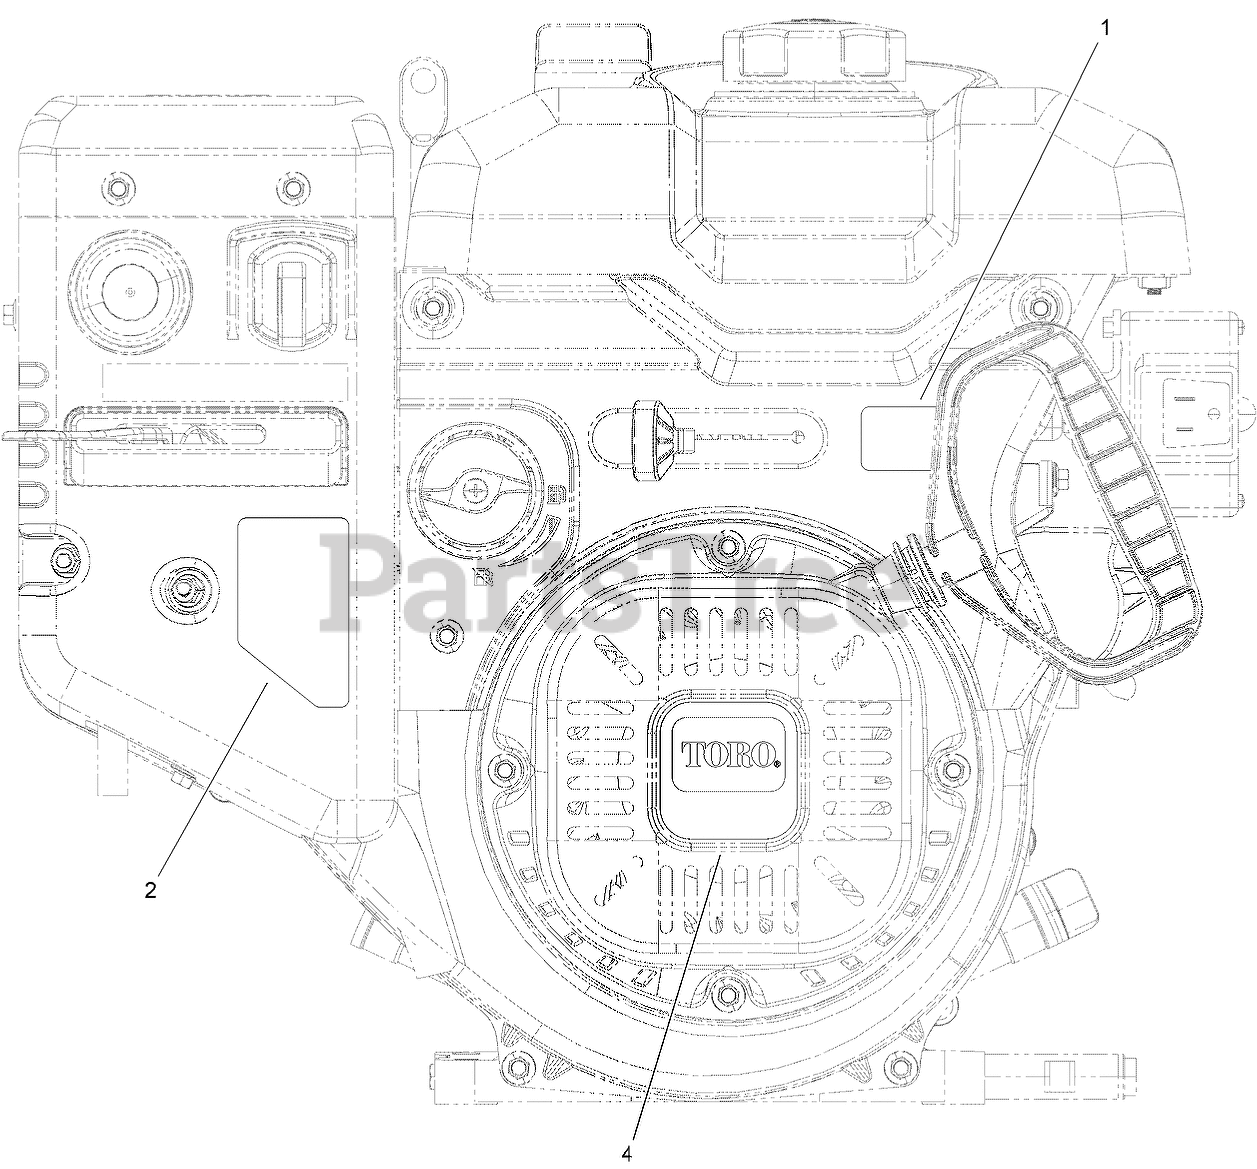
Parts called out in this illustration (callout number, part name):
1	DECAL-THROTTLE
2	DECAL-CONTROL, ENGINE
4	DECAL-RECOIL
